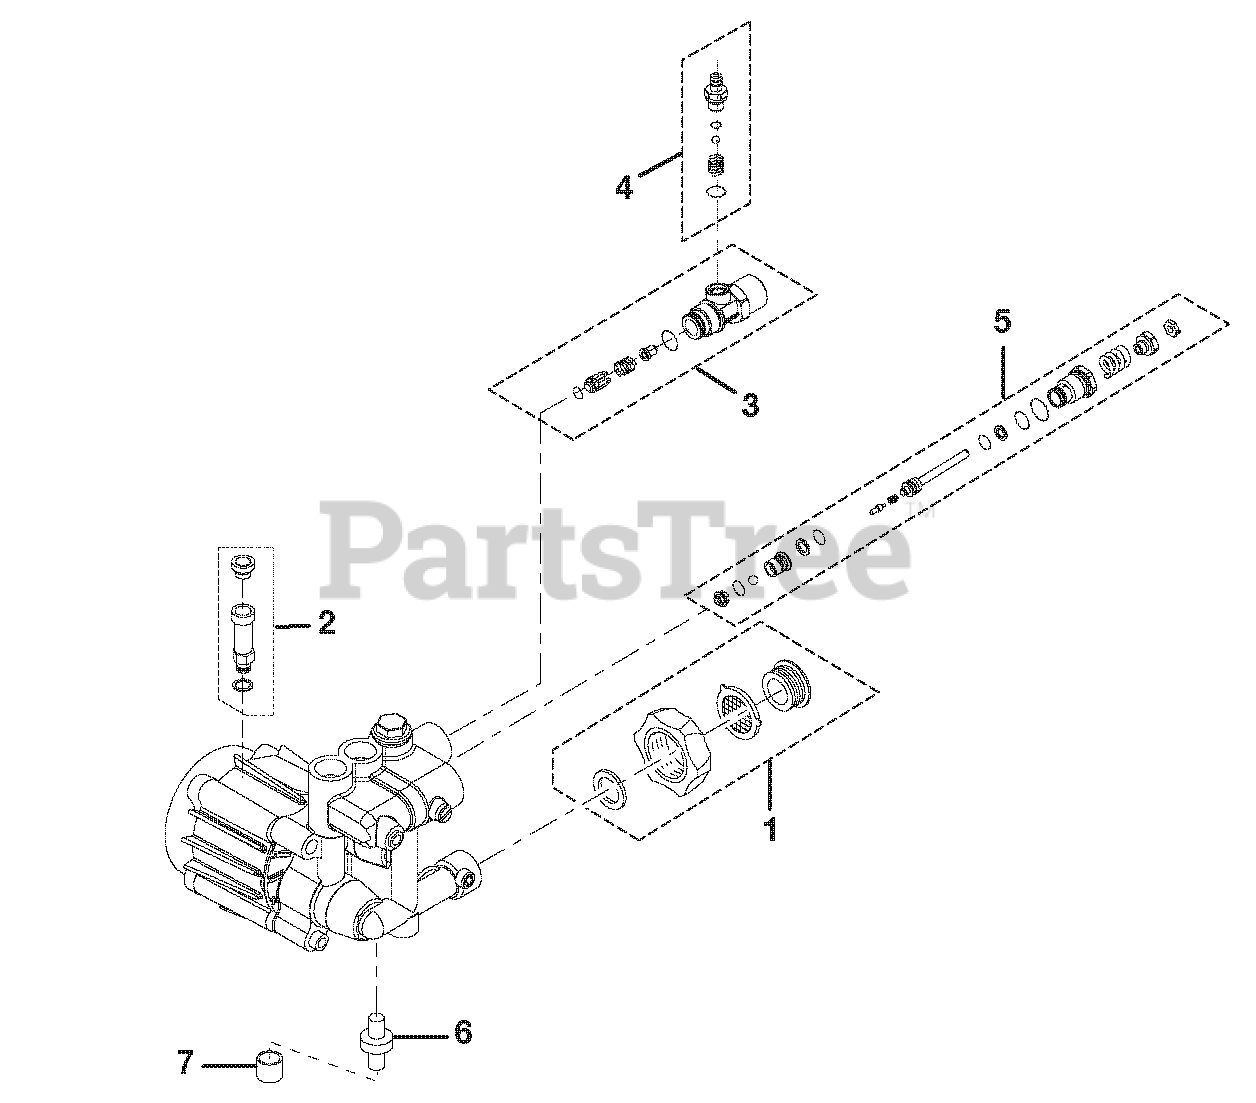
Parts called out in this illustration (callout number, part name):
1	GARDEN HOSE KIT
2	OIL BREATHER VALVE KIT
3	OUTLET CONNECTOR KIT
4	DETERGENT SUCTION KIT
5	BY-PASS VALVE KIT
6	THERMAL RELIEF VALVE
7	RUBBER TUBE
